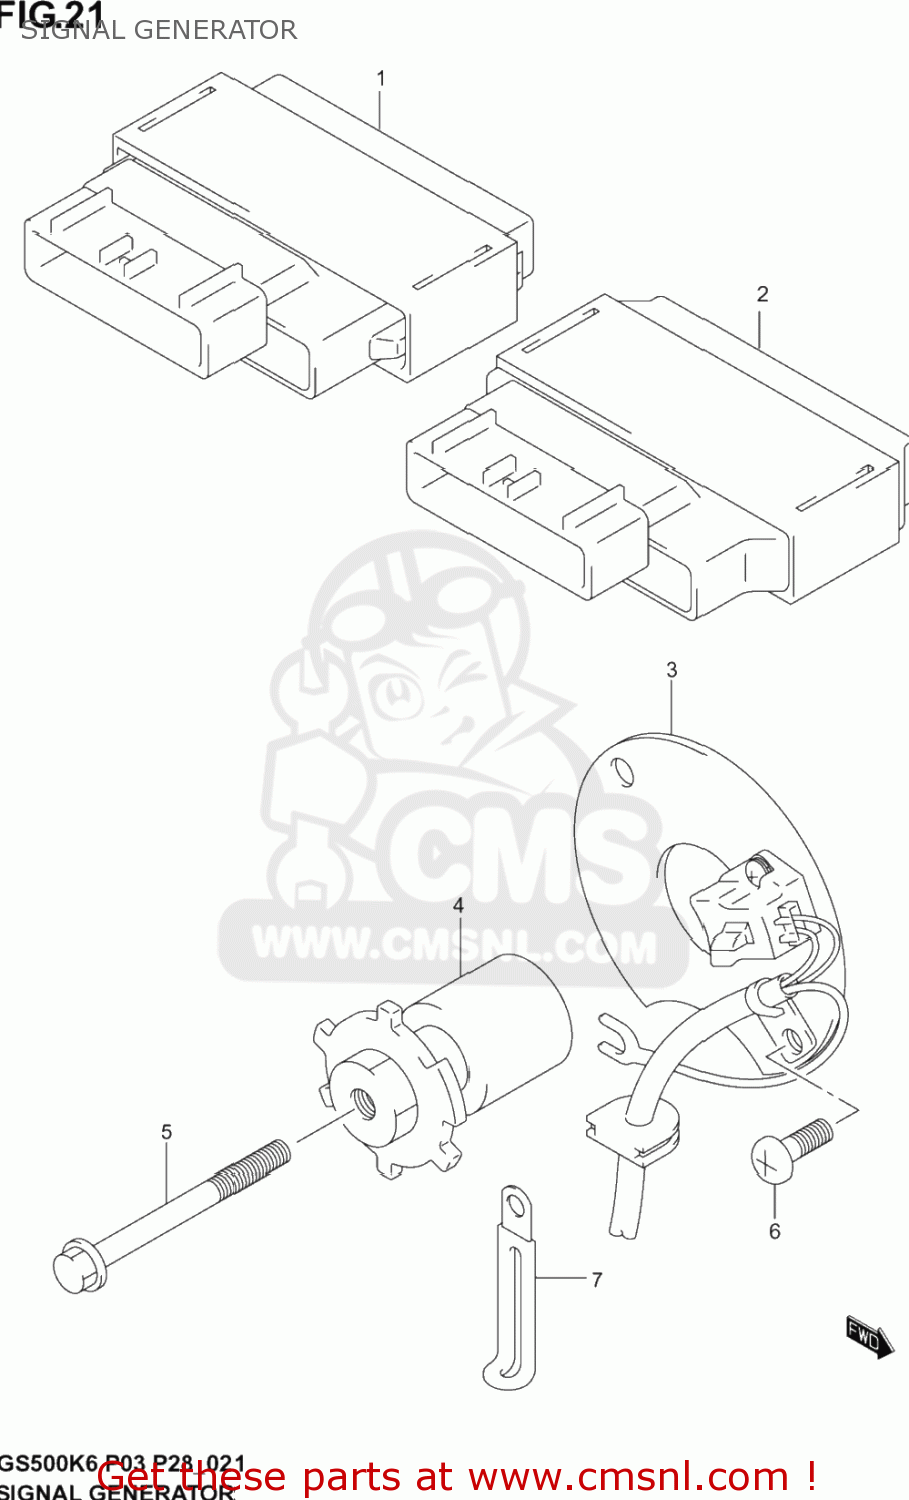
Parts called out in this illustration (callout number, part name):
1	IGNITOR ASSY
2	IGNITOR ASSY
3	SIGNAL GENERATOR ASSY
4	ROTOR,SIGNAL
5	BOLT(6X60)
6	SCREW
7	CLAMP(L:45)
